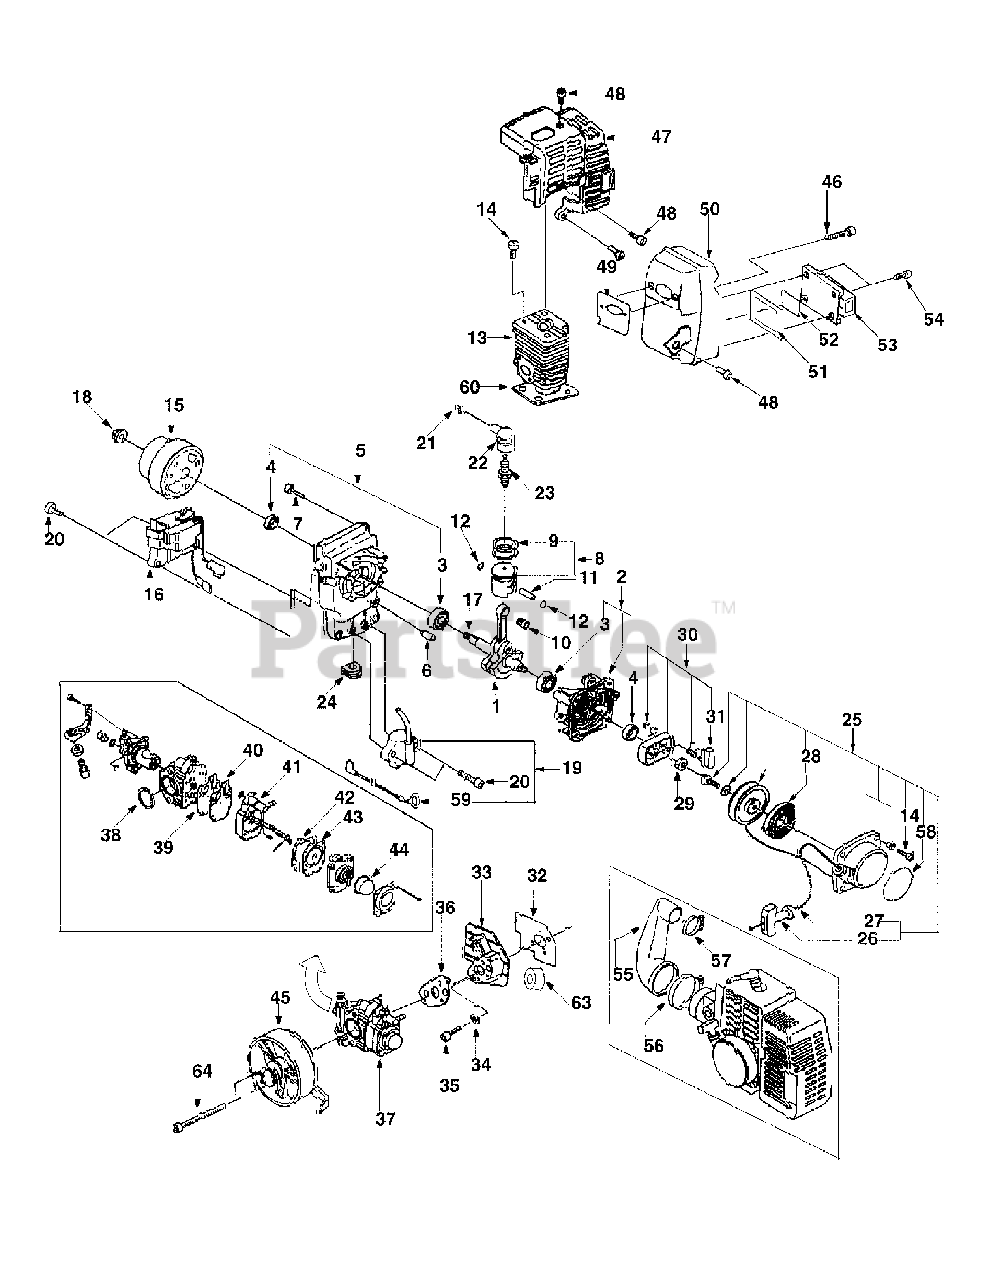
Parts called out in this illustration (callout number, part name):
1	Crankshaft
2	Crankcase Ass'y
3	Ball Bearing; 6202
4	Oil Seal
5	Crankcase Ass'y
6	Dowel Pin
7	Bolt; M5x30
8	Piston Ass'y
9	Ring, Piston
10	Needle, Bearing
11	Pin, Piston
12	Clip, Piston Pin
13	Cylinder
14	Bolt; M5x16
15	Flywheel, Magneto
16	CDI Unit
19	Coil Ass'y, Ignition
20	Bolt; M4x16
22	Cap, Plug
23	Plug, Spark
25	Recoil Ass'y
26	Knob, Starter
27	Rope, Starter
28	Spring, Spiral
30	Pulley, Starter
32	Gasket, Insulator
33	Insulator
34	Washer
35	Bolt; M5X25
36	Gasket, Carburetor
37	Carburetor Ass'y
38	Gasket
39	Gasket
40	Diaphragm, Pump
41	Body, Pump
42	Gasket
43	Diaphragm, Pump
45	Case Compl
46	Bolt; M5x58
48	Bolt; M5x12
49	Gasket, Muffler
51	Gasket, Baffle Plate
52	Arrester
53	Plate, Baffle
54	Bolt; M4x6
55	Elbow, Intake
58	Trade Mark
59	Harness, Wire
60	Gasket, Cylinder
61	Gasket Kit
62	Valve, Float
64	Bolt; M5x50
67	Spring, Return
